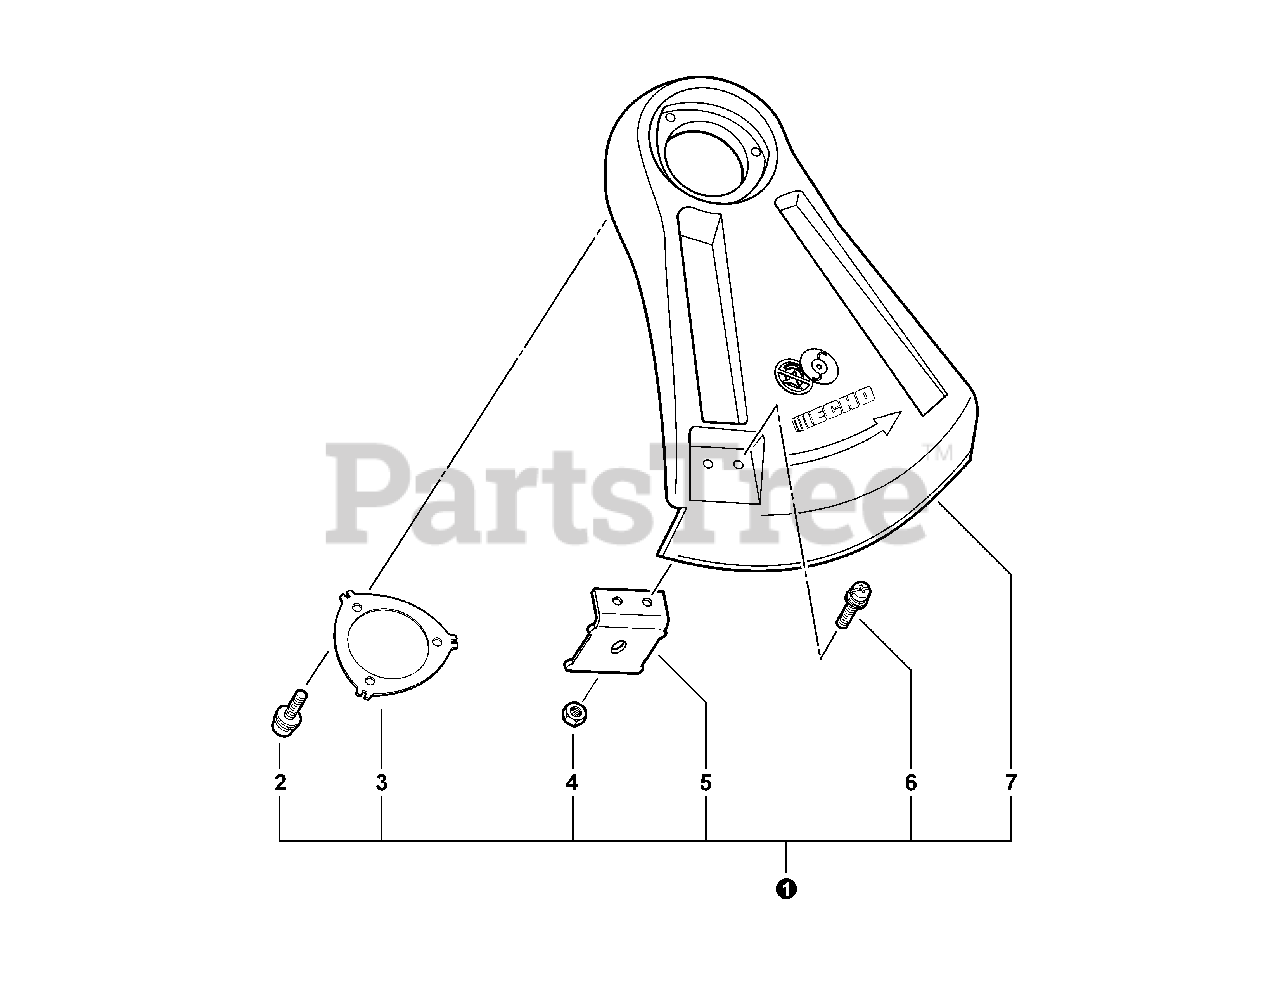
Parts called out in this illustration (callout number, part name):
1	DEBRIS SHIELD KIT
2	BOLT, TORX 5×16
3	PLATE, SHIELD Ø49.5 MM
4	NUT M5
5	CUTTER, LINE
6	BOLT, TORX 5×12
7	SHIELD, DEBRIS PLASTIC
